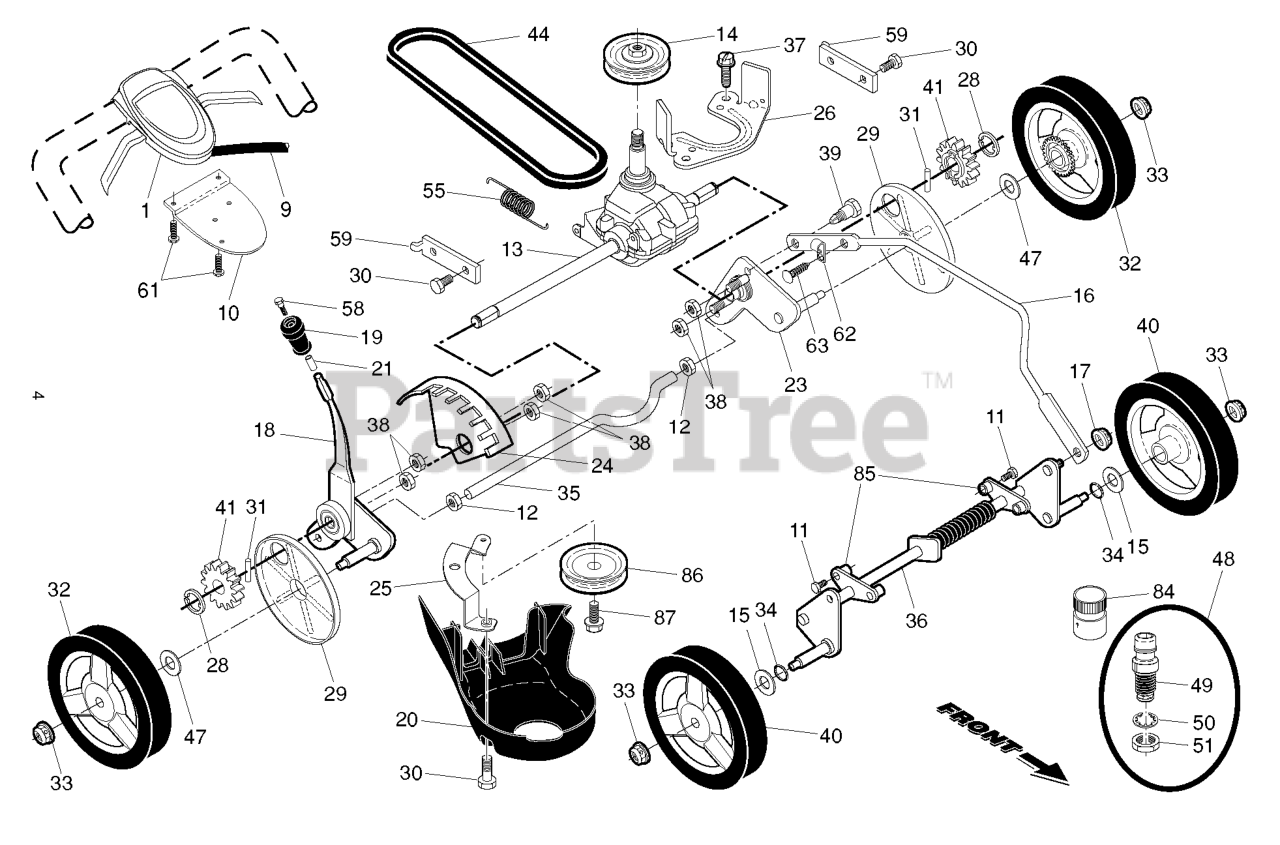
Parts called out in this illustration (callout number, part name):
1	RP CTRL.AW2.22+RQD.BS.GRY/BLK
9	CABLE.DRIVE.RWD.WALK.
10	BRACKET.DRIVE.CONTR.GEN2.BLACK
11	SCREW.HX.13X.750
12	NUT.HEX.1/2-20
13	TRANSMISSION.22+AWD.WALK.MOWER
15	WASHER.FLAT.1/2
16	ROD.CONNECTING.RGD.22+.HW.BLAC
17	NUT.LOCK.5/16-18
18	KIT.SELECTOR.ASM.437869
19	KNOB.SEL.SPRING.22+.SP.RIB.BLK
20	COVER.REAR.DRIVE.22+2013
21	SCREW.PLASTIC.ANCHOR.5/16
23	ADJUSTER.ARM.ASM.AX.RT.SP.ZC
24	BRACKET.WHL.ADJ.9.POS.W/PAD
25	BRACKET.DRIVE.COVER.RGD.
26	BRACKET.TRANS.BELT.KEEPER.BZP
28	E-RING 7/16 RE
29	COVER.DUST.WHEEL.INNER.WALK
30	BOLT.5/16HEX.WHS.HD
31	PAWL, DRIVE
32	WHEEL.8X1.75.3SPK.RAD3.GREY
33	NUT.HEX.FLANGE.3/8-16.LO(3 2)
34	O-RING..070X.487.NEOPRENE
35	AXLE.REAR.RGD
36	AXLE.ASM.FRONT.RGD.CLEAR.ZINC
38	NUT.HEX.FLANGE.1/4
39	SHOULDER BOLT SEMI GIMLET PT.
40	WHEEL & TIRES ASSY, FRONT
41	PINIION.14.TOOTH.RGD
44	RP.BELT.DRIVE.RGD.SS.WALK
47	WASHER FLUT
48	KIT.WASH-OUT.PORT.ZINC.WALK
49	WASHOUT.PORT.ZINC.RGD.22+
50	WASHER.LOCK.INTERNAL.TOOTH
51	LOCKNUT.HEX.WITH.O-RING
55	SPRING.RETURN.AUTO.
58	SCREW.12-14X1.500
59	BRACKET.SUPPORT.22+RWGD.BZP
61	SCREW, PHILLIPS HEAD 10 X 5/8
62	CLIP.CABLE.BLK
63	FASTENER.PUSH.O.250X0.783
84	COUPLING.QUICK CONNECT
85	BRACKET.FRT.AXLE.SUPPORT
86	RP PULLEY.AWD.IDLER
